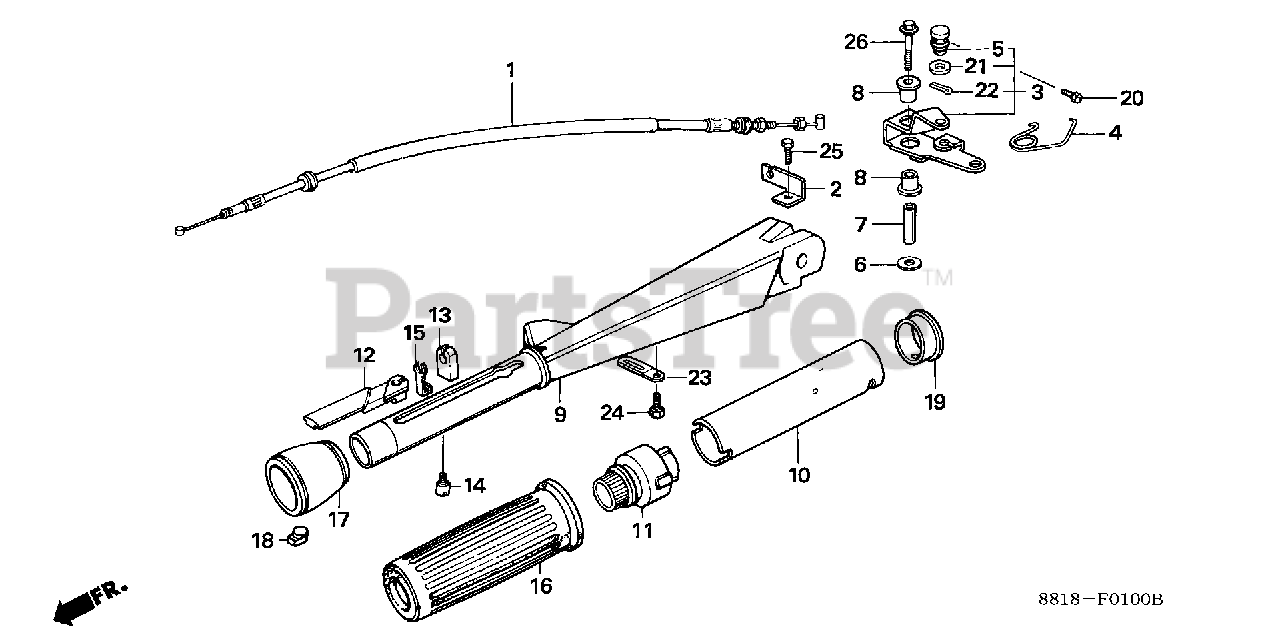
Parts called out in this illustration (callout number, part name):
1	CABLE, THROTTLE
2	HOLDER, CABLE
3	ARM, THROTTLE
4	SPRING, THROTTLE ARM
5	HOLDER, STARTER ROD
6	WASHER, PIVOT
7	COLLAR, PIVOT
8	BUSH, SHAFT
9	HANDLEBAR *NH282MU* (OYSTER SILVER METALLIC-U)
10	PIPE, GRIP
11	NUT, GRIP FRICTION
12	HINGE, THROTTLE WIRE
13	HOLDER, THROTTLE CABLE
14	STOPPER, GRIP PIPE
15	STOPPER, CABLE
16	RUBBER, GRIP
17	COVER, GRIP PIPE
18	GROMMET, HANDLE COVER
19	GUIDE B, GRIP PIPE
20	BOLT, SLOTTED (4X6)
21	WASHER, PLAIN (6MM)
22	PIN, SPLIT (2.0)
23	CLIP B, CORD
24	BOLT, HEX. (6X12)
25	BOLT, HEX. (6X12)
26	BOLT, FLANGE (6X35)
